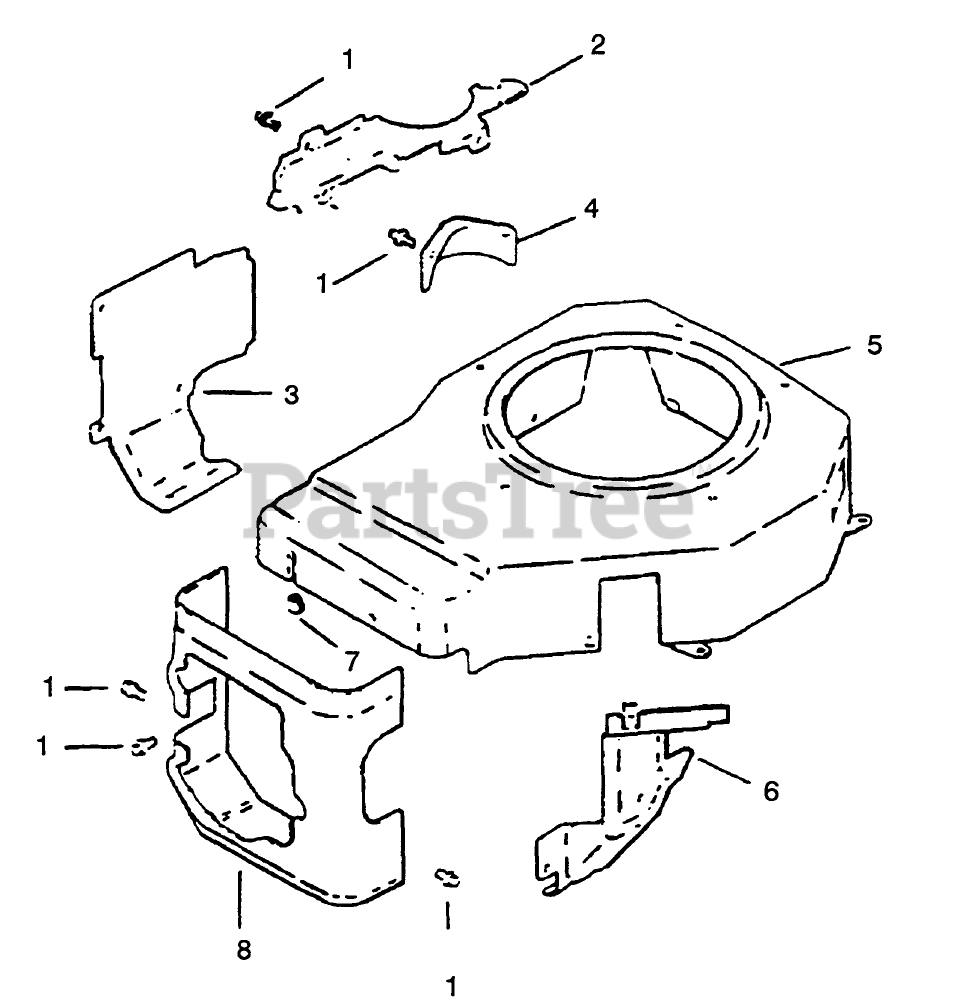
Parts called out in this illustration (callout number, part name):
2	Plate-Blower Housing (Only On: 72042,72043,72062,72063)
3	Baffle-Cylinder Barrel (Only On: 72042, 72063, 72062, 72043)
4	Cover-Starter
5	Housing-Blower
6	Baffle-Carburetor (Only On: 72042, 72043, 72062, 72063)
7	Grommet-Blower Housing (Only On: 72042, 72043, 72062, 72063)
8	Baffle-Cylinder Head
